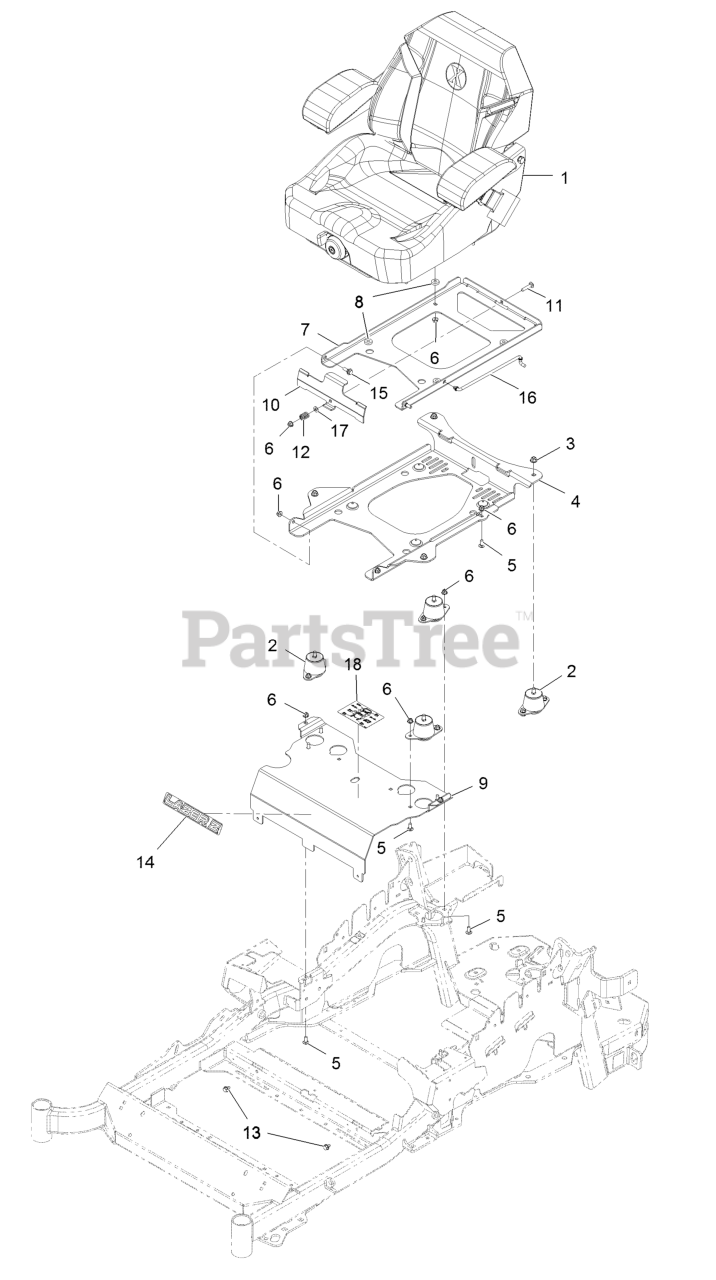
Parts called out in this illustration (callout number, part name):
1	Kit-Suspension Seat
2	Isolator-Seat
3	Nut-Nyloc 3/8-16 Flg
4	Plate-Tilt, Seat Support
5	Bolt-Carriage 5/16-18 X 3/4 Short Neck
6	Nut-Nyloc 5/16-18 Flg
7	Plate-Frame, Seat
8	Spacer-Pin, Mounting
9	Panel-Front, Seat Mount
10	Plate-Latch, Seat
11	Bolt-Carriage 5/16-18 X 1 1/2
12	Spring-Compression
13	Screw-HWH 5/16 X 1/2 Tf
14	Decal, Lazer Model
15	Screw-Shoulder
16	Rod-Prop
17	Washer-5/16 SAE
18	Decal-Service Aid
